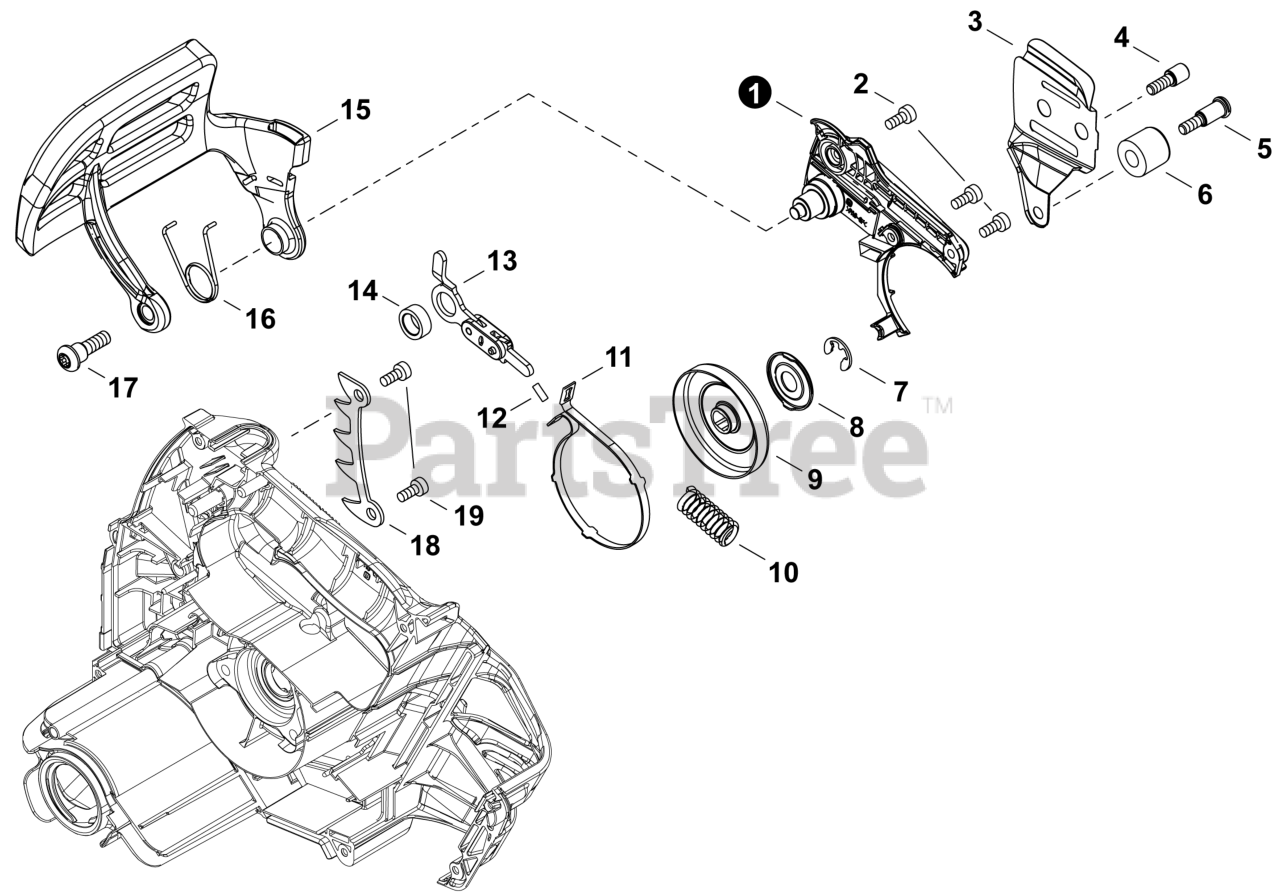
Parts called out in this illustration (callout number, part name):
1	COVER, BRAKE
2	BOLT, TORX 4x12
3	PLATE, GUIDE - INNER
5	BOLT 5x12
6	CATCHER, CHAIN
7	E-RING 8.1
8	WASHER 10
9	DRUM, CLUTCH .325"
10	SPRING, COMPRESSION
11	BAND, BRAKE
13	CONNECTOR, BRAKE
14	COLLAR 8
15	LEVER, BRAKE
16	SPRING, TORSION
17	BOLT 5x13
18	SPIKE, BUMPER
19	BOLT, TORX 5x12
